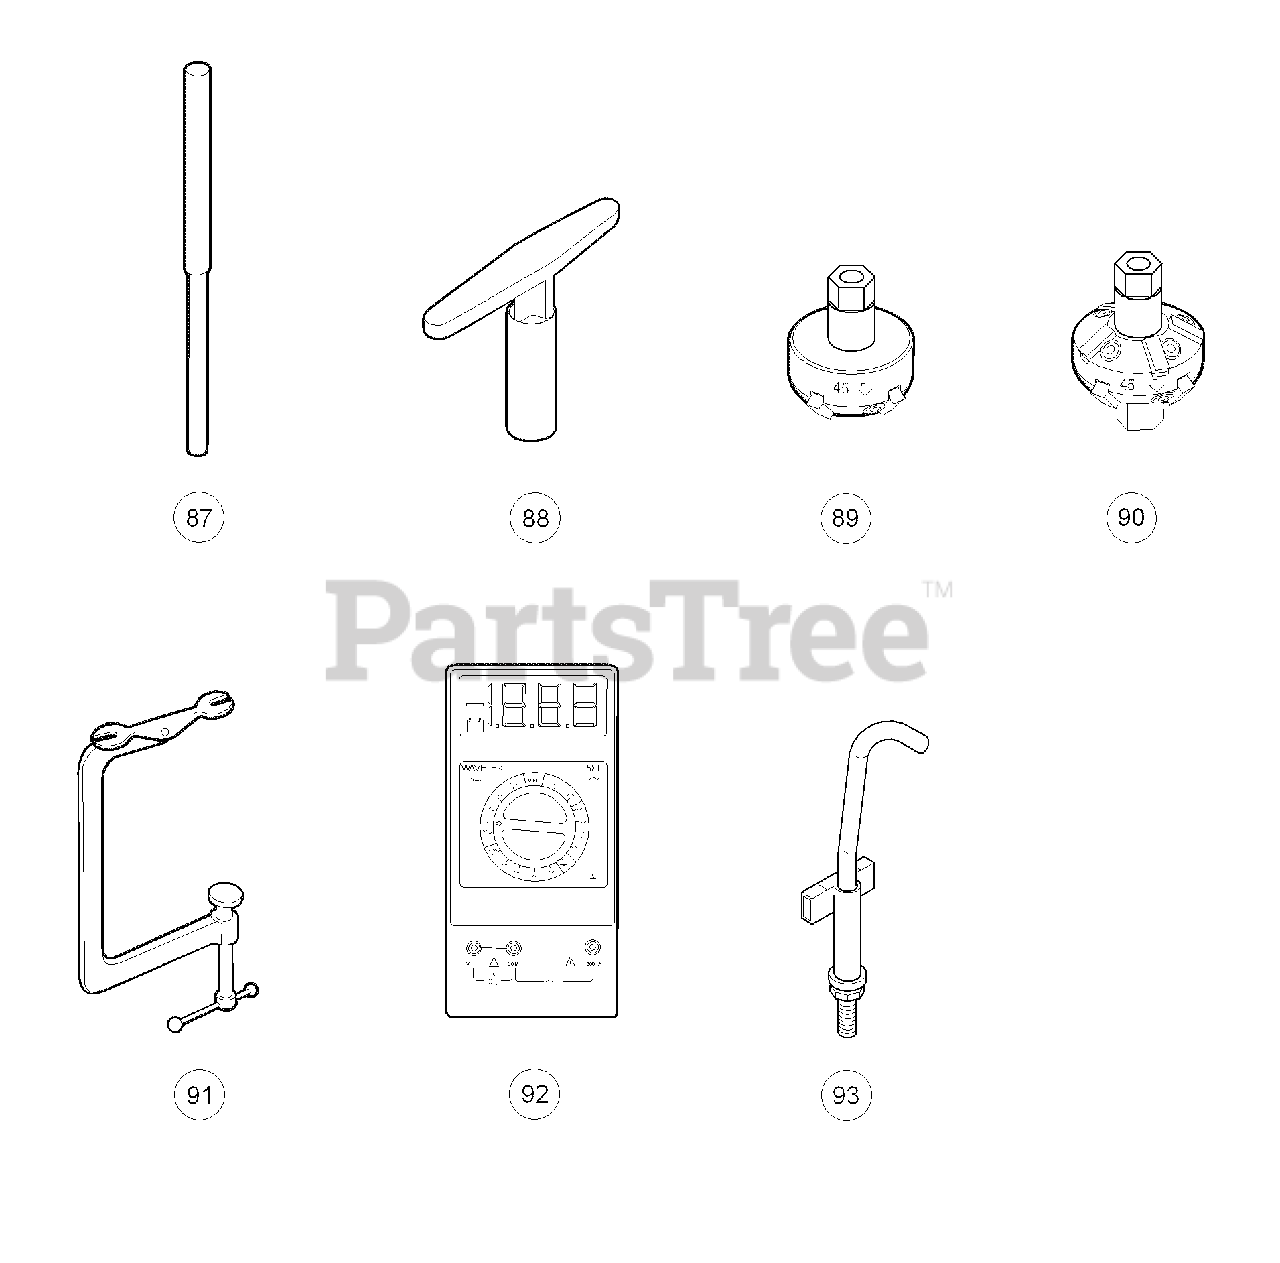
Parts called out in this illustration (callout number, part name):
86	Valve Seat Cutter Guide
87	Valve Seat Cutter T-Wrench
88	Valve Seat Cutter, 45°
89	Valve Seat Cutter, 45°/30°
90	Valve Spring Compressor
91	Volt Ohm Meter
92	Tool, Tensioning, Starter Generator
